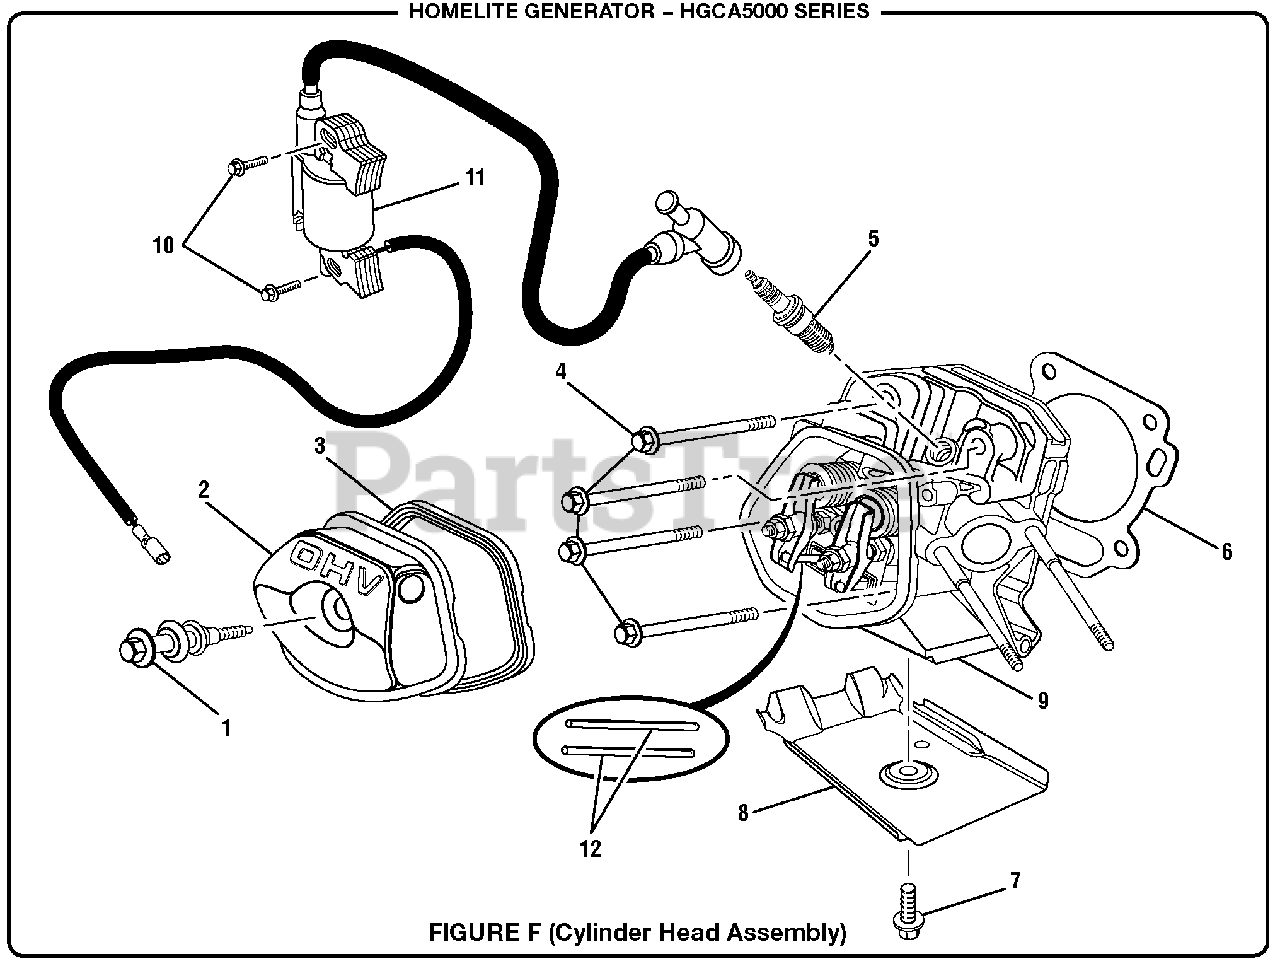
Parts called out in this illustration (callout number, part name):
1	Bolt Assembly (Valve Cover)
2	Valve Cover
3	Valve Cover Gasket
4	Bolt (M10 x 80 mm, Cylinder Head)
5	Spark Plug (Champion F7TC
6	Cylinder Head Gasket
7	Bolt (M6 x 12 mm, Flange Hd.)
8	Lower Cover (Cylinder Head)
9	Cylinder Head Assembly (Incl. Key Nos. 1-8)
10	Bolt (M6 x 30)
11	Ignition Coil Assembly
